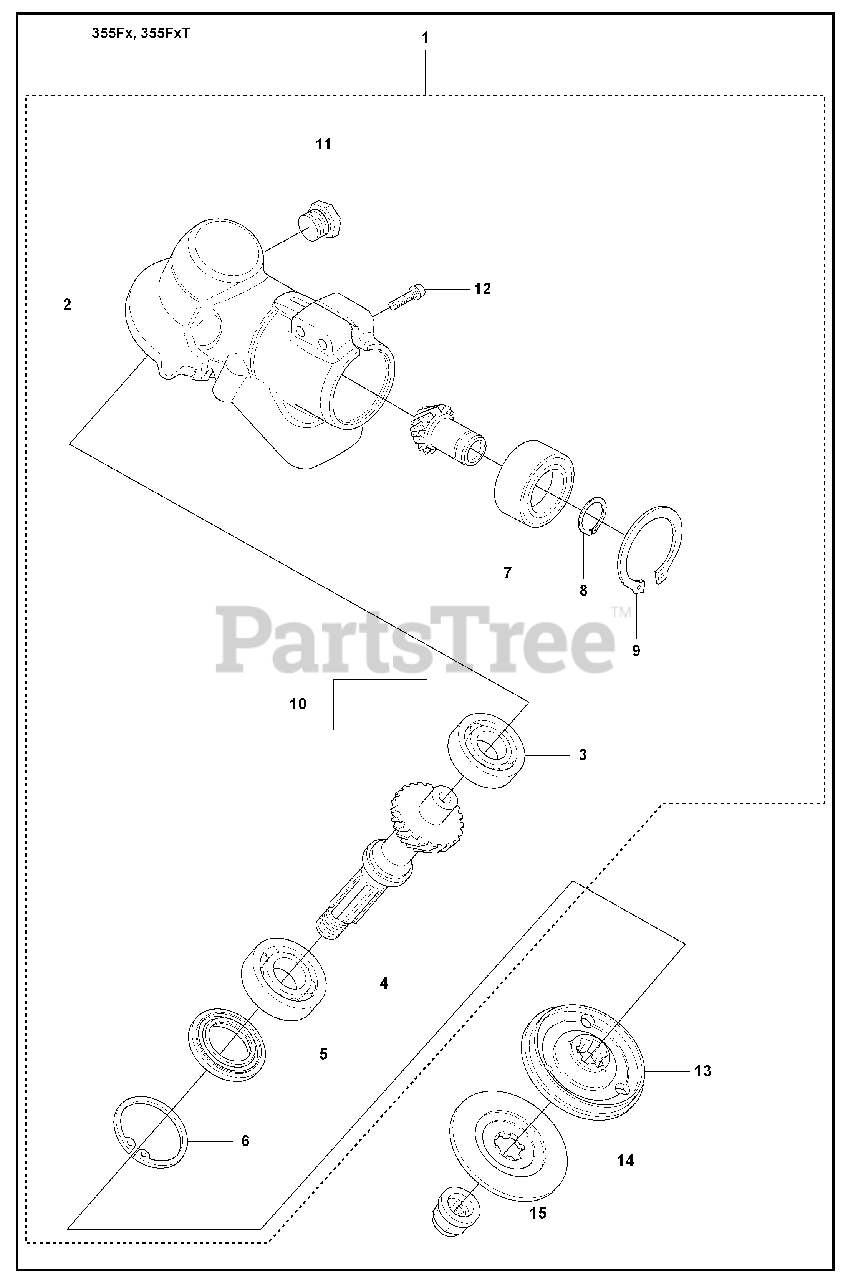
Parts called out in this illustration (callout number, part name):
1	RP BEVEL GEAR
2	%GEAR HOUSING
3	BALL BEARING
4	BALL BEARING
6	RETAINING RING SGH 35
8	RETAINING RING SGA 15
9	RETAINING RING
10	BEVEL GEAR
14	SUPPORT FLANGE
15	BLADE NUT
